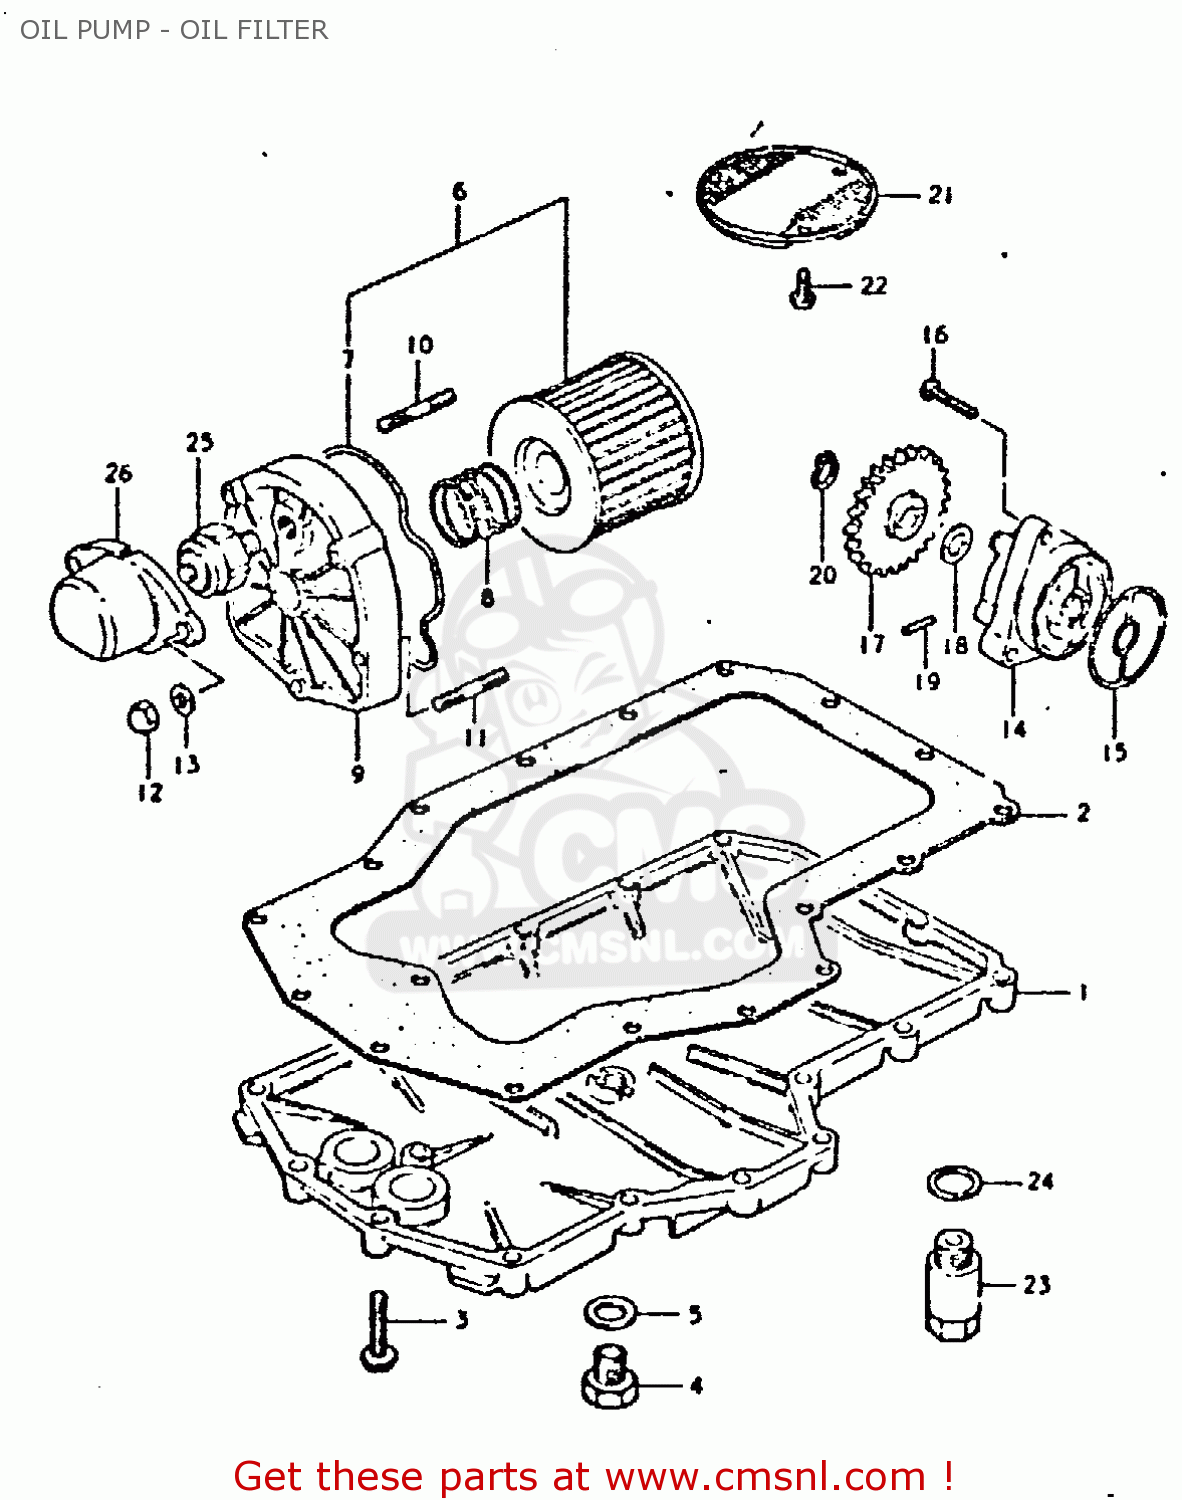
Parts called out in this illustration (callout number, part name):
1	PAN,OIL
2	GASKET,OIL PAN (MCA)
3	BOLT
4	PLUG
5	GASKET(14X19.2X2) (NAS)
6	FILTER SET, ENGINE OIL
7	O RING,OIL FILTER CHAMBER CAP
8	SPRING
9	CAP,ENGINE OIL FILTER
10	STUD BOLT
11	STUD 6X25
12	NUT
13	WASHER
14	PUMP ASSEMBLY,OIL
15	O-RING,OIL PUMP
16	SCREW
17	GEAR,ENG OIL PUMP DRIVEN
18	SHIM
19	PIN(4X15.8)
20	CIRCLIP
21	STRAINER,ENGINE OIL
22	SCREW 6X12
23	VALVE ASSEMBLY,OIL RELIEF
24	WASHER
25	SWITCH ASSEMBLY
26	COVER,OIL PRESSURE SWITCH
